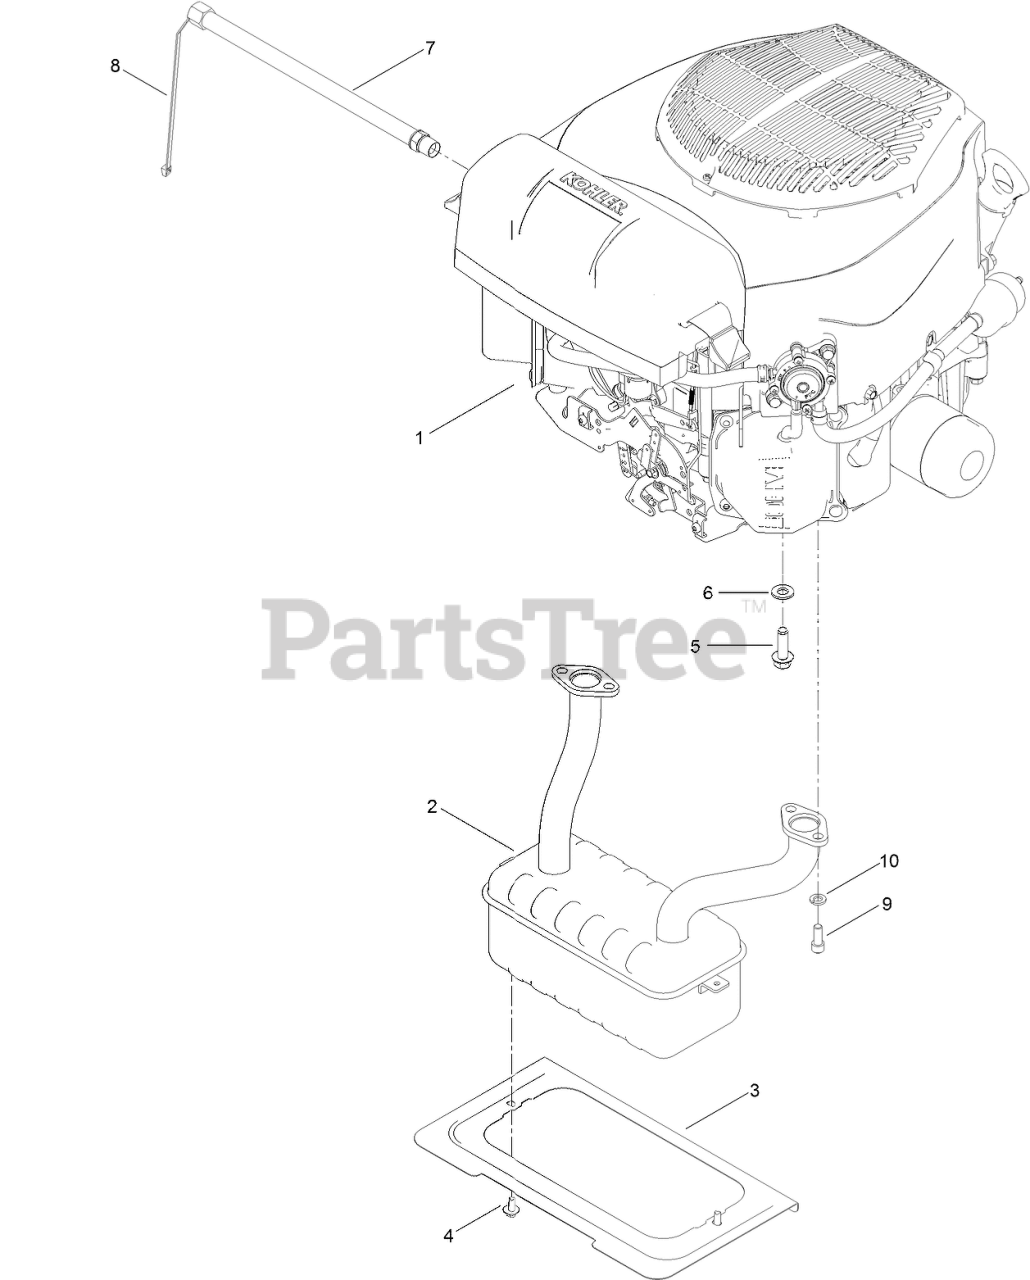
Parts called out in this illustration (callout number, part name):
2	MUFFLER
3	SHIELD-HEAT
4	SCREW-HHFTF
5	SCREW-THD
6	WASHER-FLAT
7	HOSE-DRAIN, OIL
8	TIE-CABLE
9	SCREW-HSH
10	WASHER-LOCK
